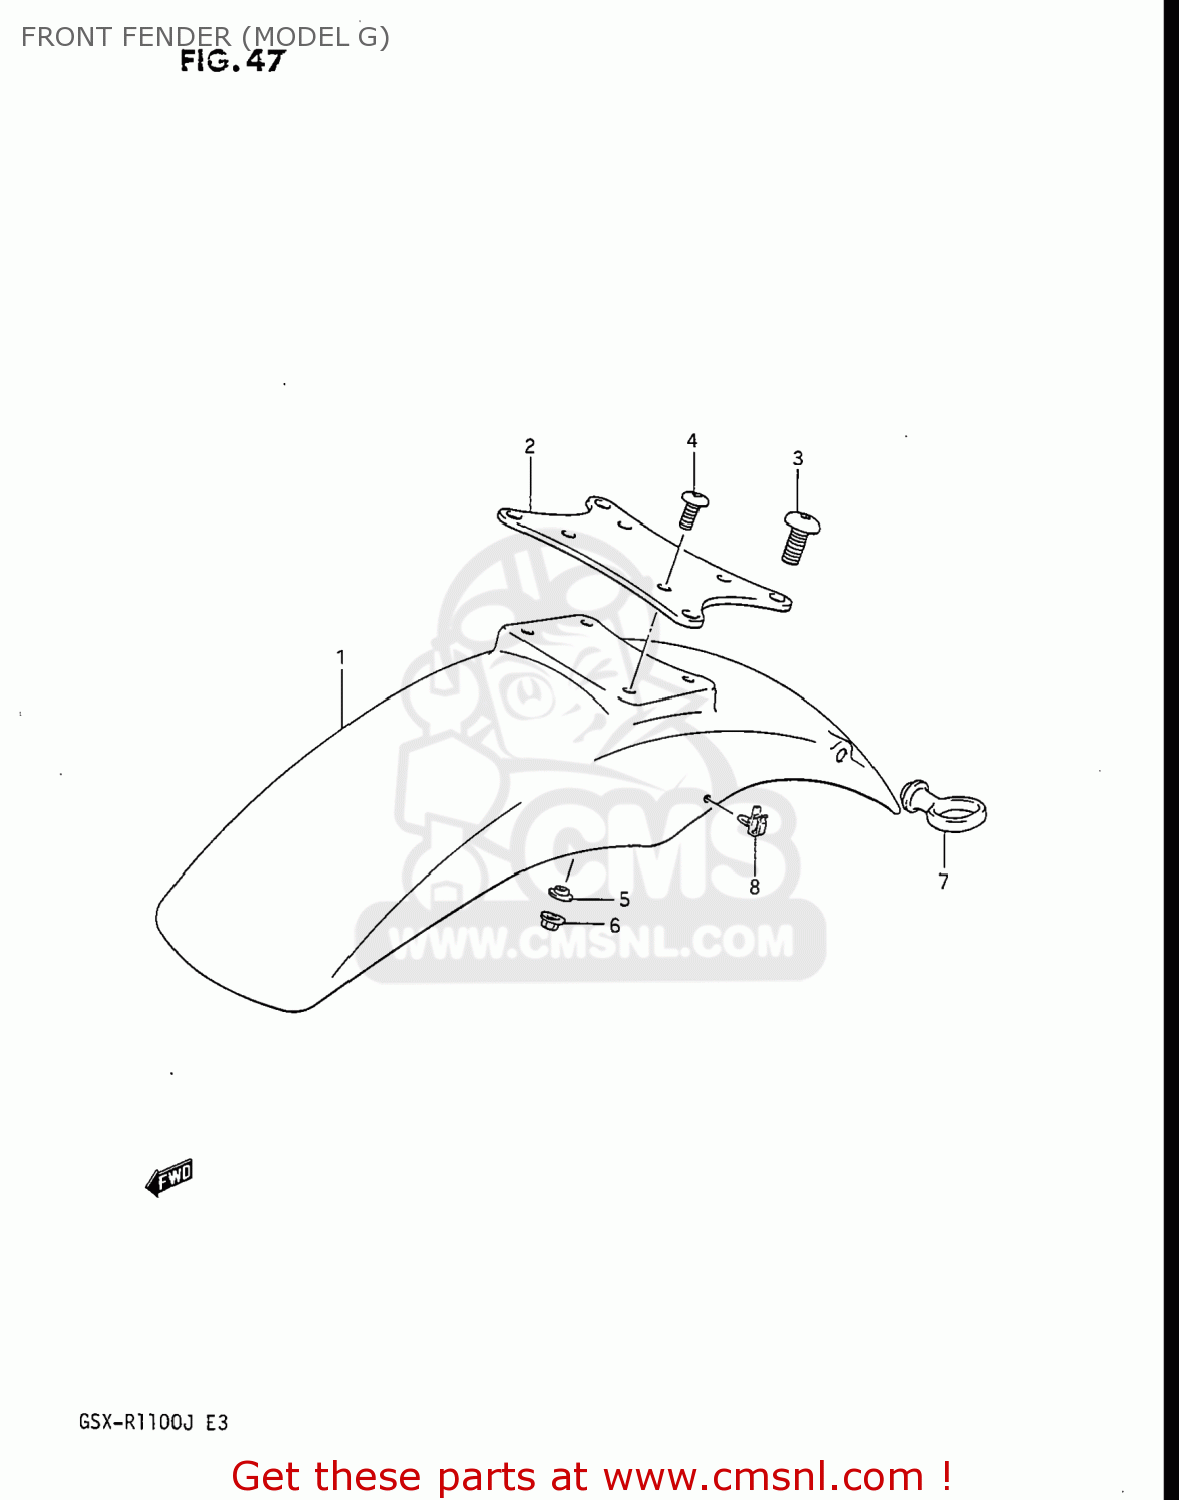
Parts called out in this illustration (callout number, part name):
1	FENDER,FRONT
2	BRACE,FRONT FENDER
3	SCREW(8X16)
4	SCREW(5X14)
5	WASHER
6	NUT
7	GUIDE,CABLE
8	CLIP
